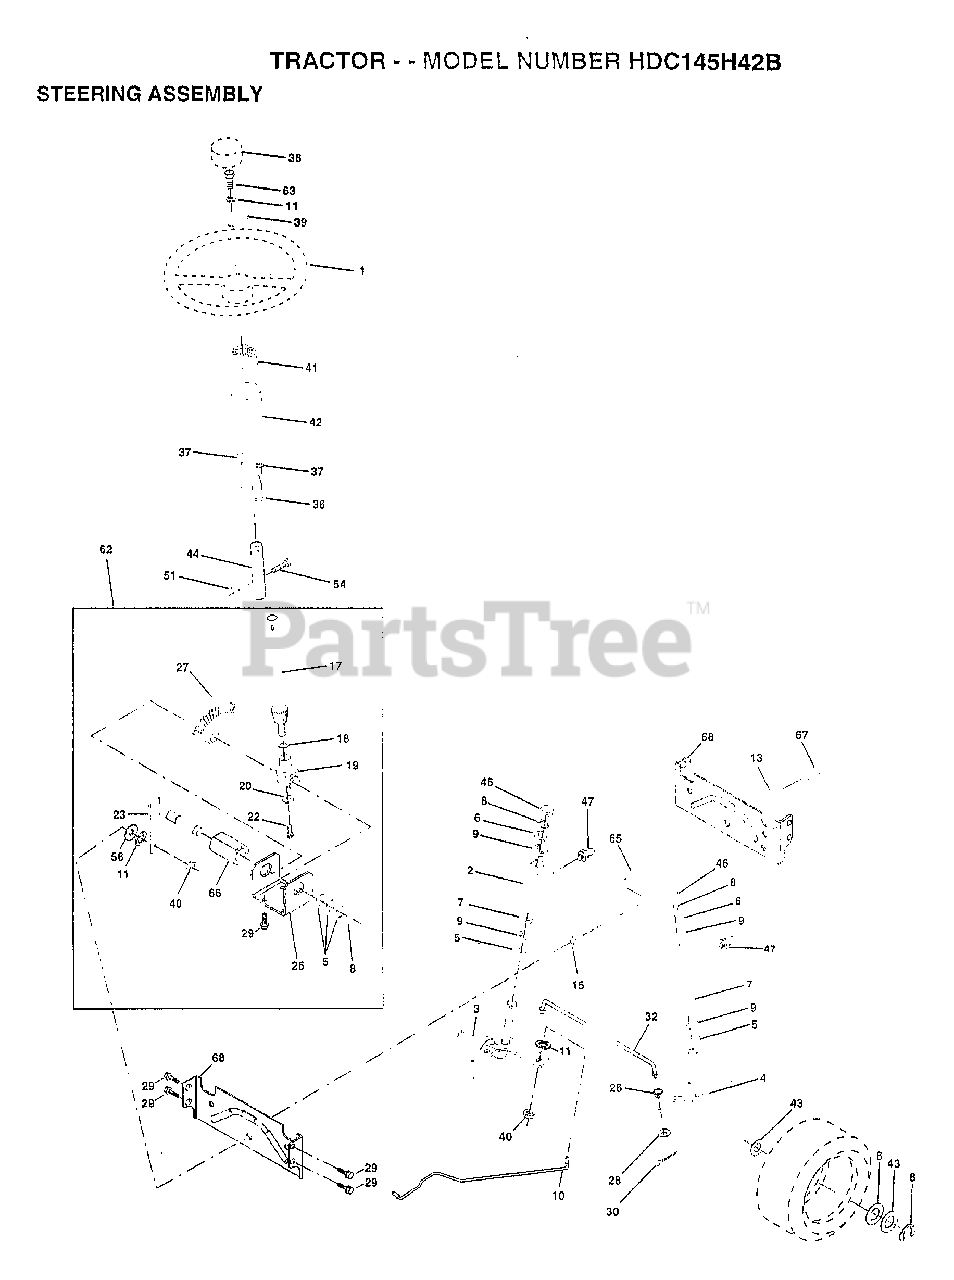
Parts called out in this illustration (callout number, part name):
1	WHEEL STR AYP BLK
2	AXLE ASM
3	SPINDLE ASM LH
4	"SPINDLE ASM,RH"
5	WASHER .T
6	WASHER
7	WASHER
8	RING
9	COL. SRTG. BEAR.
10	DRAGLINK-STAMPED
11	LOCKWASHER
13	BEARING AXLE
15	"NUT-LOC,FLANGE LT"
17	SHAFT ASM STEERIN
18	THRUST WASHER
19	SUPPORT.SHAFT
21	LOCKWASHER
22	CONFLICT W/PART #
25	BRKT-STEERING
26	BUSHING.DRAGLINK
27	GEAR SECTOR
28	WASHER
29	SCREW
30	COTTER PIN
32	TIE ROD
36	BUSHING.STEERING
37	"SCREW-TT,10-32 FL"
38	CAP STEER AYP
39	WASHER T
40	GRIPCO NUT
41	ADAPTER LT
42	BOOT.STEER.PL
43	WASHER
44	EXT SHAFT STEERIN
46	CAP
47	ZERK M
51	NUT
54	BOLT
62	KIT STEERING ASM
63	BOLT
65	SPACER AXLE
66	"BEARING-ARM,PITMA"
67	BOLT
68	BRACE AXLE
